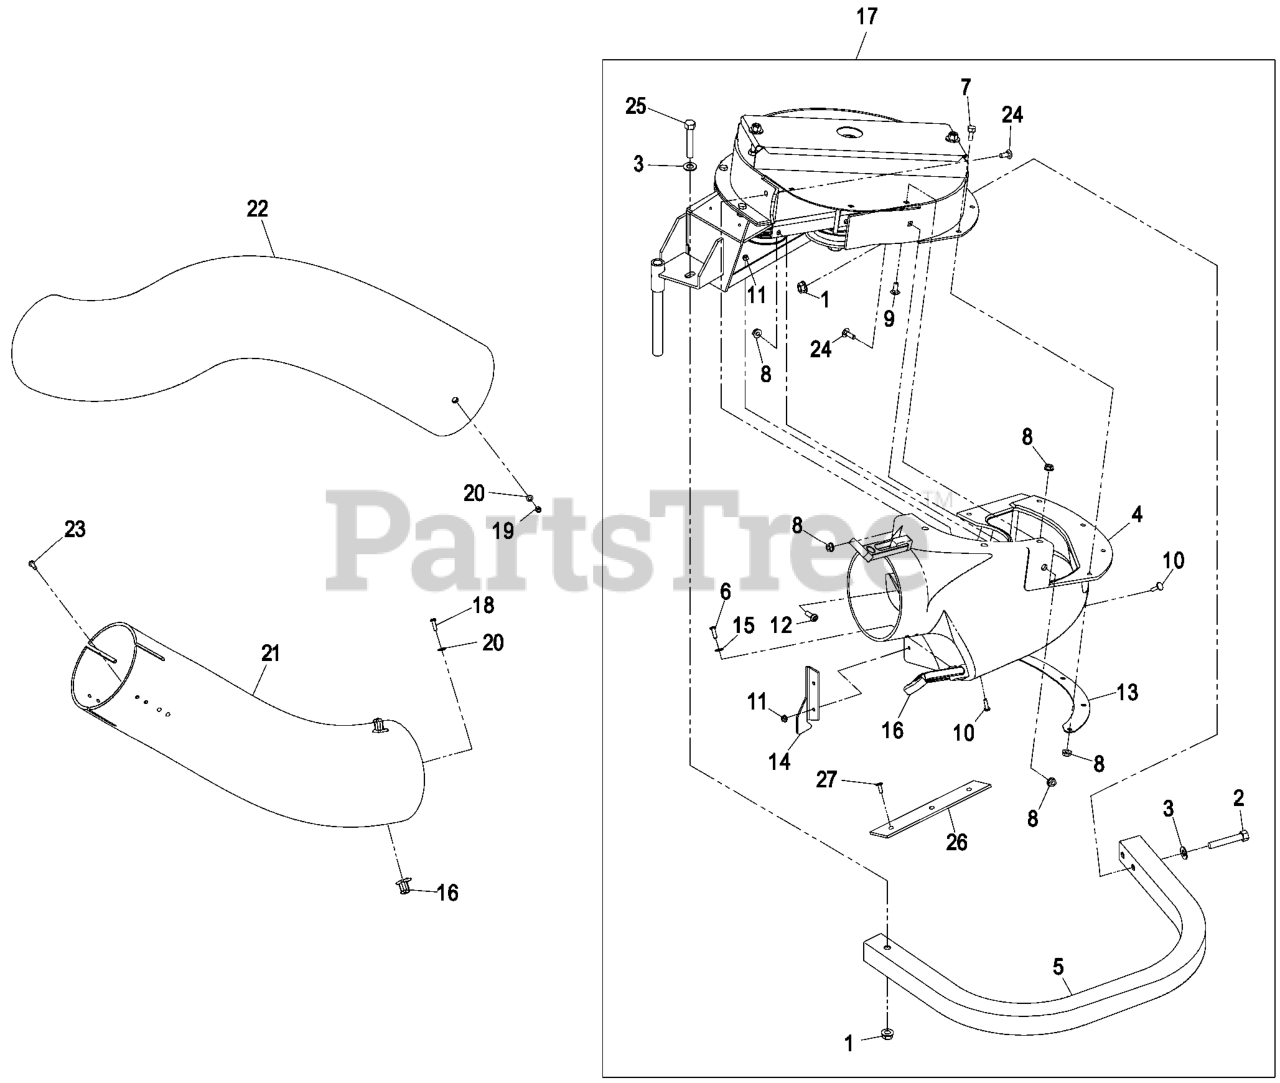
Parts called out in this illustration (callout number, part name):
1	NUT-HHF, WHIZ
2	SCREW-HH
3	WASHER-FLAT
4	ASM,BLOWER CHUTE LHP
4	ASM,BLOWER CHUTE SMALL
6	SCREW-PPH
7	SCREW-HH
9	SCREW-CARR
10	SCREW-HEAD, TRUSS
13	PLATE-BACKING, BLOWER
14	PLATE, FILLER
15	WASHER-FLAT
16	LATCH DRAW
17	ASM,BLOWER
17	ASM,BLOWER 52 SERVICE ONL
18	SCREW-PPH
19	NUT-LOCK, NI
20	WASHER-FLAT
21	KIT,LOWER TUBE
22	TUBE-UPPER
23	SCREW-HWH
24	BOLT-CARR
25	SCREW-HH
26	PLATE-REINFORCEMENT
27	RIVET-BLIND
